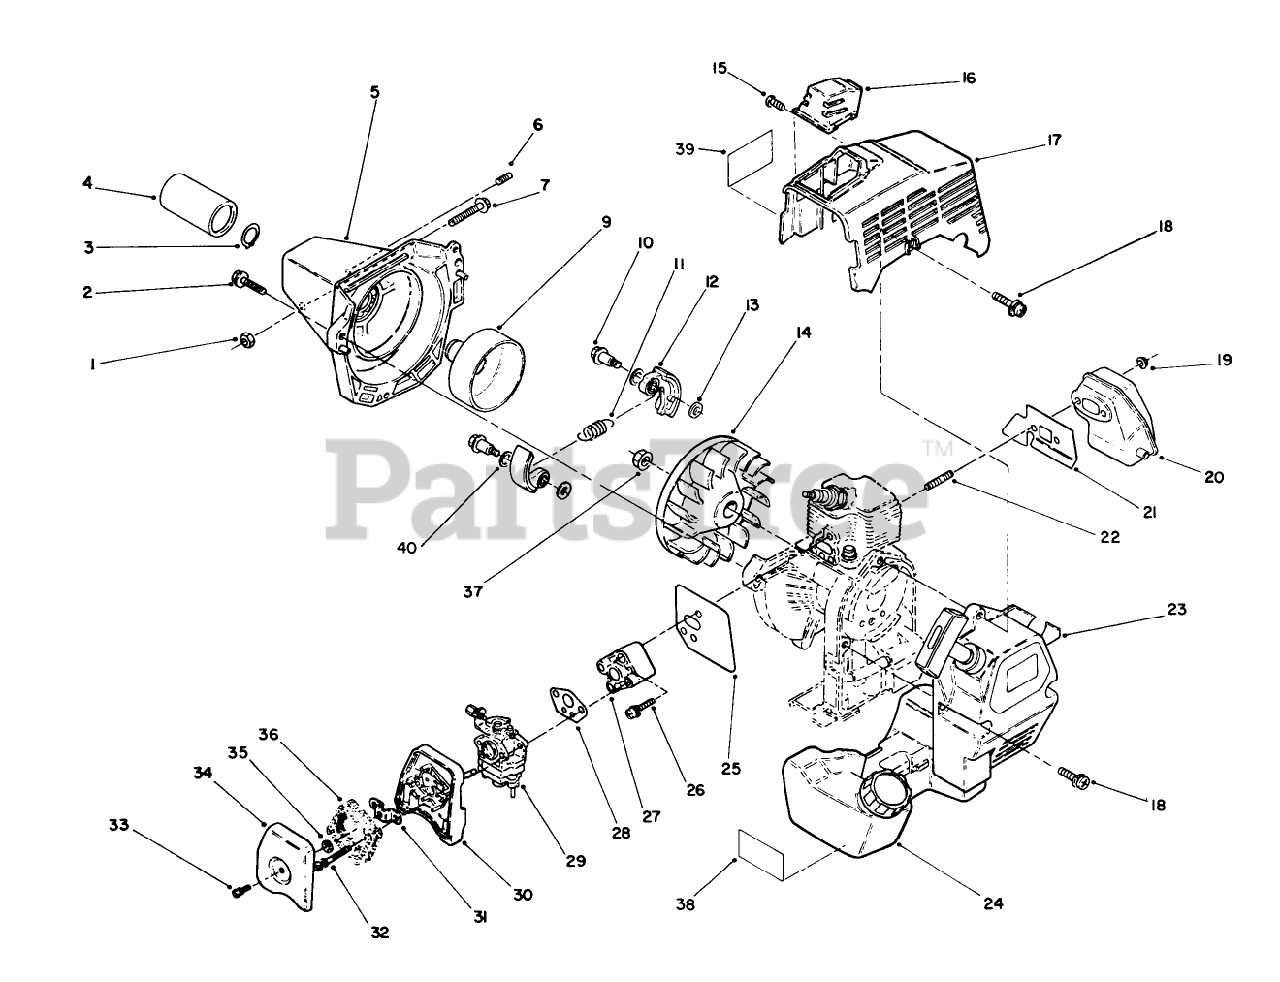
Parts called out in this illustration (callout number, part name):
2	BOLT AND WASHER
3	SNAPRING
4	POLE SPACER
5	Housing-Clutch
6	SETSCREW
7	Screw/Washer
9	CLUTCH DRUM
10	CLUTCH BOLT
11	Spring
12	SHOE, CLUTCH
13	WASHER
14	Fan
15	SCREW & WASHER
16	SPARK PLUG GUARD
17	TOP SHIELD
18	SCREW & WASHER
19	MUFFLER FLANGE NUT
20	MUFFLER
21	MUFFLER GASKET
22	MUFFLER STUD
23	RECOIL ASSEMBLY
24	Fuel Tank Assembly
25	INSULATOR GASKET
26	SCREW & WASHER
27	INSULATOR
28	CARBURETOR GASKET
29	Carburator Assembly
30	CLEANER CASE
31	BRACKET
32	SCREW W/ WASHER
33	SCREW & WASHERE
34	CLEANER COVER
36	CLEANER ELEMENT
38	DECAL - FUEL TANK
39	DECAL-SURFACE, HOT
40	SPRING WASHER
